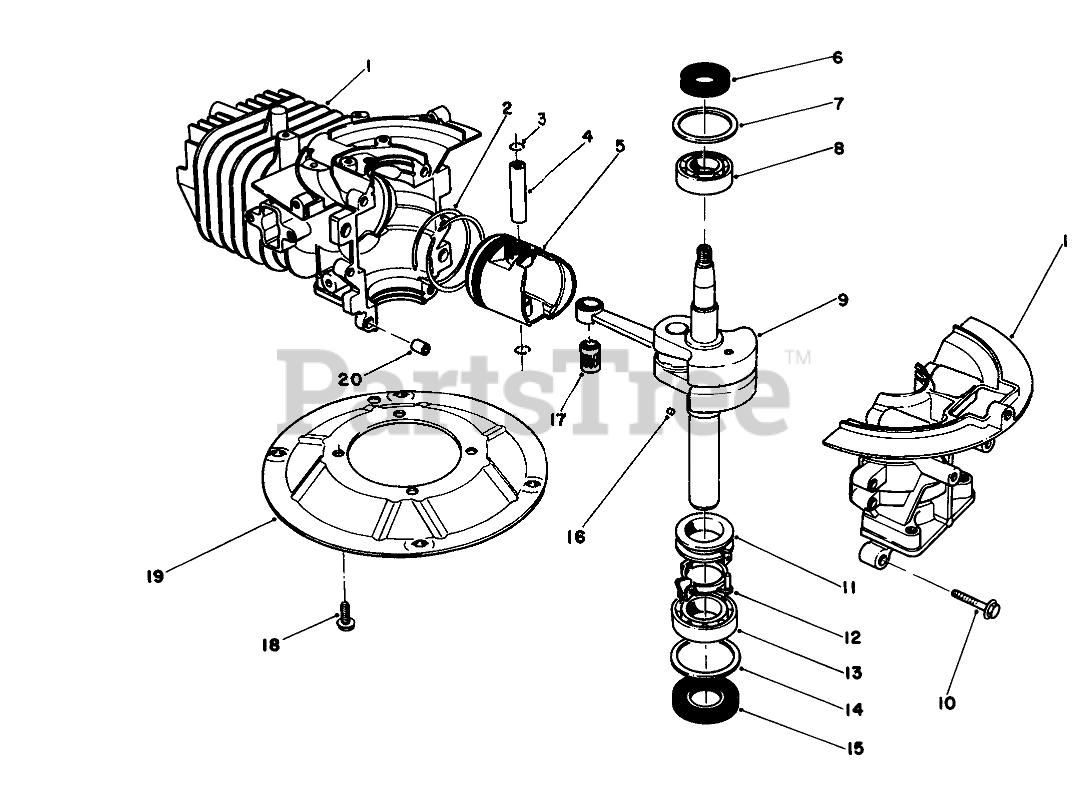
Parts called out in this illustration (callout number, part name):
1	CRANKCASE
2	RING SET
4	Pin-Wrist
5	Piston
6	OIL SEAL
7	WASHER-UPPER
8	BEARING-UPPER
9	CRANKSHAFT ASM
11	SPACER
12	BRACKET
13	LOWER BRG
14	WASHER-LOWER
15	SEAL-OIL
17	BEARING
19	PLATE-MOUNTING
